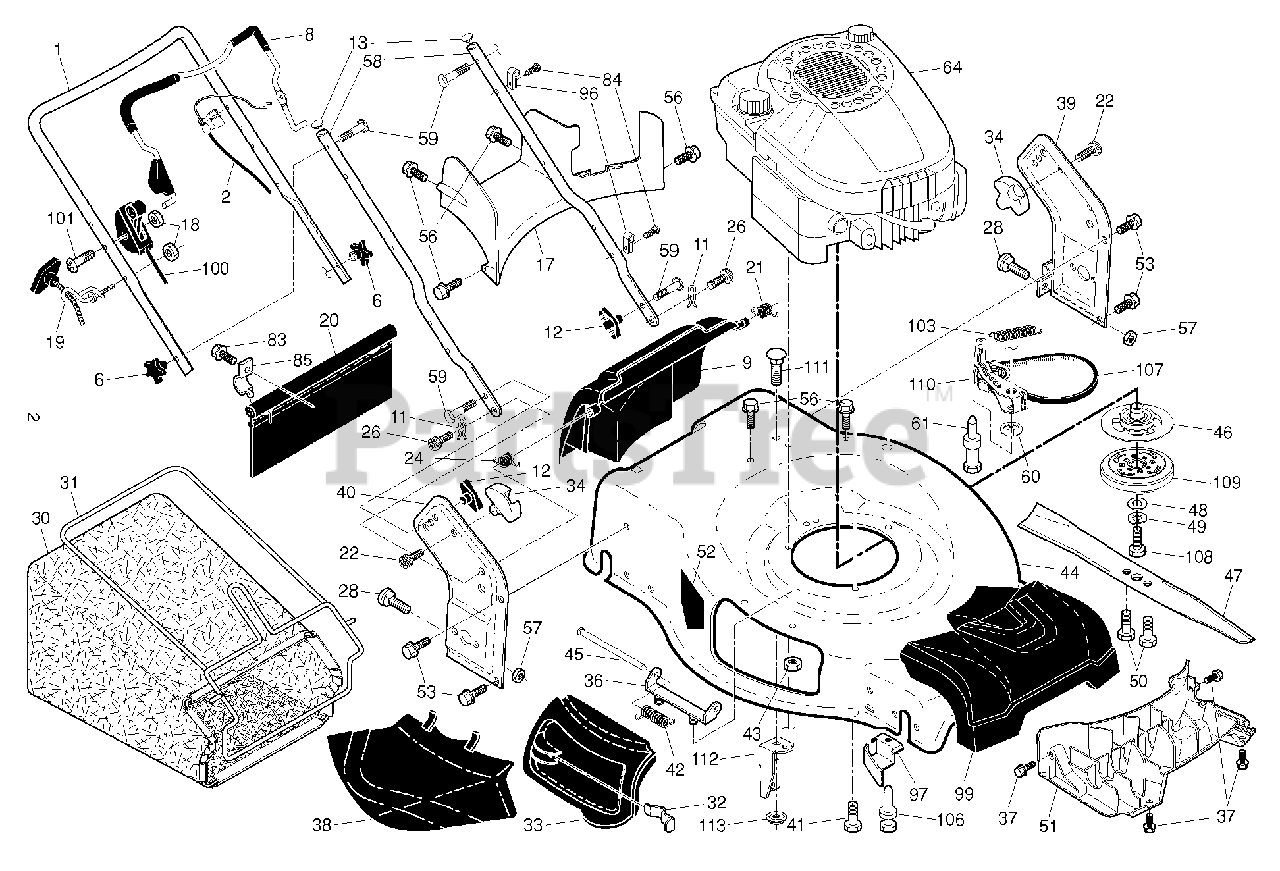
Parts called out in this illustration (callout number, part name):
1	HANDLE.UPPER.3.POS.BS.AW2.GREY
2	CABLE.BBC.22+.AW2.BS.ERGO.WALK
6	KNOB.HANDLE.PLASTIC.STAR.BLACK
8	RP.BAIL.ASM.BBC.NTRL.ERGO.ORNG
9	DOOR.REAR.ASM.22+.HUSQ.FG/RGD
11	COTTER.HAIRPIN.DOOR/HANDLE.PIV
12	KNOB, DEFLECTOR
13	PLUG.PLASTIC.7/8".14-20.GAUGE
17	RP.BAFFLE.REAR.22+.RGD.PL
18	NUT
19	RB GUIDE.ROPE.STD.BLK.ZIN WSL
20	SKIRT.REAR.22PLUS.RGD.LW(2 2MC
21	SPRING.LH.BLACK
22	SCREW.PAN.HEAD.#10
24	SPRING.RH.GRAY
26	SCREW,DOOR/HANDLE.PIVOT
28	BOLT
30	GBAG.A3610247T.SILV.HUSWT.BLUE
31	RB FRAME.GBAG.22PLUS
32	LATCH.DOOR.ZINC
33	DOOR.MULCH.22 PLUS.HUSQ.GREY
34	BRACKET.GRASSBAG.ATTACHING.BLK
36	BRACKET.ASM.HINGE.21.FWGD.
37	SCREW.HI-LO.5/16 X.75
38	DEFLECTOR.CLIPPING.22.BLACK
39	BRACKET.ASM.HNDL.LT.22+.GREY
40	BRACKET.ASM.HNDL.RT.22+.GREY
41	BOLT 3/8-16X1-1/8
42	SPRING.TORSION
43	NUT.HEX.FLANGE.1/4
44	HOUSING.22+RG.MC.WO.BBC.ORANGE
45	ROD.HINGE.21
46	PULLEY.BBC.DRIVING
47	BLADE.22.4-N-1.BBC.RUST PREV
48	WASHER.CRANK.BOLT
49	LOCKWASHER
50	BOLT.BLADE
51	BAFFLE.FRONT.22+PLASTIC.(2 2)
52	DANGER DECAL
53	BOLT.5/16HEX.WHS.HD
56	SCREW.HX.13X.750
57	NUT.FLANGE.5/16
58	HANDLE.LOWER.22+BT.2PC.GRY
59	BOLT, HANDLE 5/16-18X1.75
60	E-RING.12MM.SHAFT
61	BOLT.BBC.TENSION.PIVOT
83	TAPPING SCREW
84	FASTENER.PUSH.O.250X0.783
85	BRACKET.SKIRT.22+.BZP
96	CLIP.CABLE.BLK
97	BRACKET.BELT.GUIDE.22+.BZP
99	COVER.ASM.FRONT.SHROUD.HUSQ.
100	CONTROL.THROTTLE.BBC
103	SPRING.BRAKE.RESET
106	BOLT.BRAKE.RESET.SPRING
107	BELT.COG.BBC
108	SCREW, HEX HD 3/8-24 X 1-3/8
109	HUB.FREE.BBC.ASSEMBLY(2 2MC)
110	ARM.BBC.TNSION.ARM.PULL(2 2MC)
112	BRACKET.CABLE MOUNTING.22+
113	NUT.FLANGE.1-4-20-SERR
